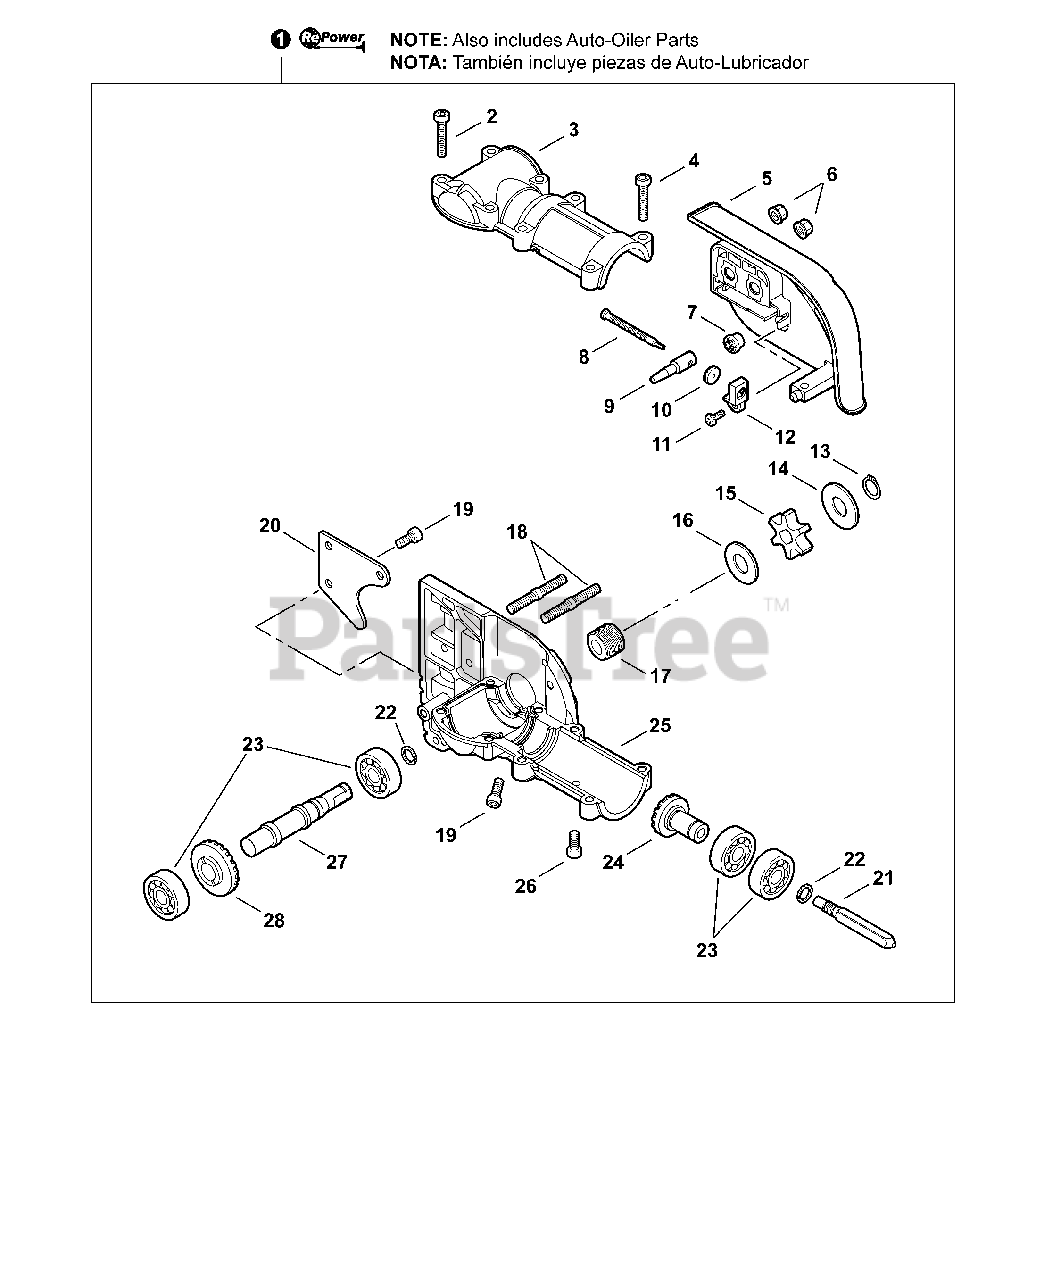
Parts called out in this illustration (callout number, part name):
1	GEAR CASE ASSY
2	SCREW M5×25
3	CASE, GEAR - UPPER Ø35
4	BOLT 5×25
5	GUARD, SPROCKET
6	NUT, FLANGE M6
7	GEAR - 14 TOOTH
9	TENSIONER, CHAIN
10	GEAR - 14 TOOTH
11	SCREW 4
12	COLLAR 8
13	RING, SNAP
14	WASHER 10
15	SPROCKET, DRIVE
16	WASHER 10.2×24.5×1.2
17	GEAR, WORM
18	BOLT, STUD 6
19	SCREW 5×10
21	CONNECTOR, DRIVE SHAFT
22	RING, SNAP Ø12
23	BEARING, BALL
24	GEAR, BEVEL - 15 TOOTH
25	CASE, GEAR
26	BOLT M5×10
27	SHAFT, GEAR
28	GEAR, BEVEL - 23 TOOTH
